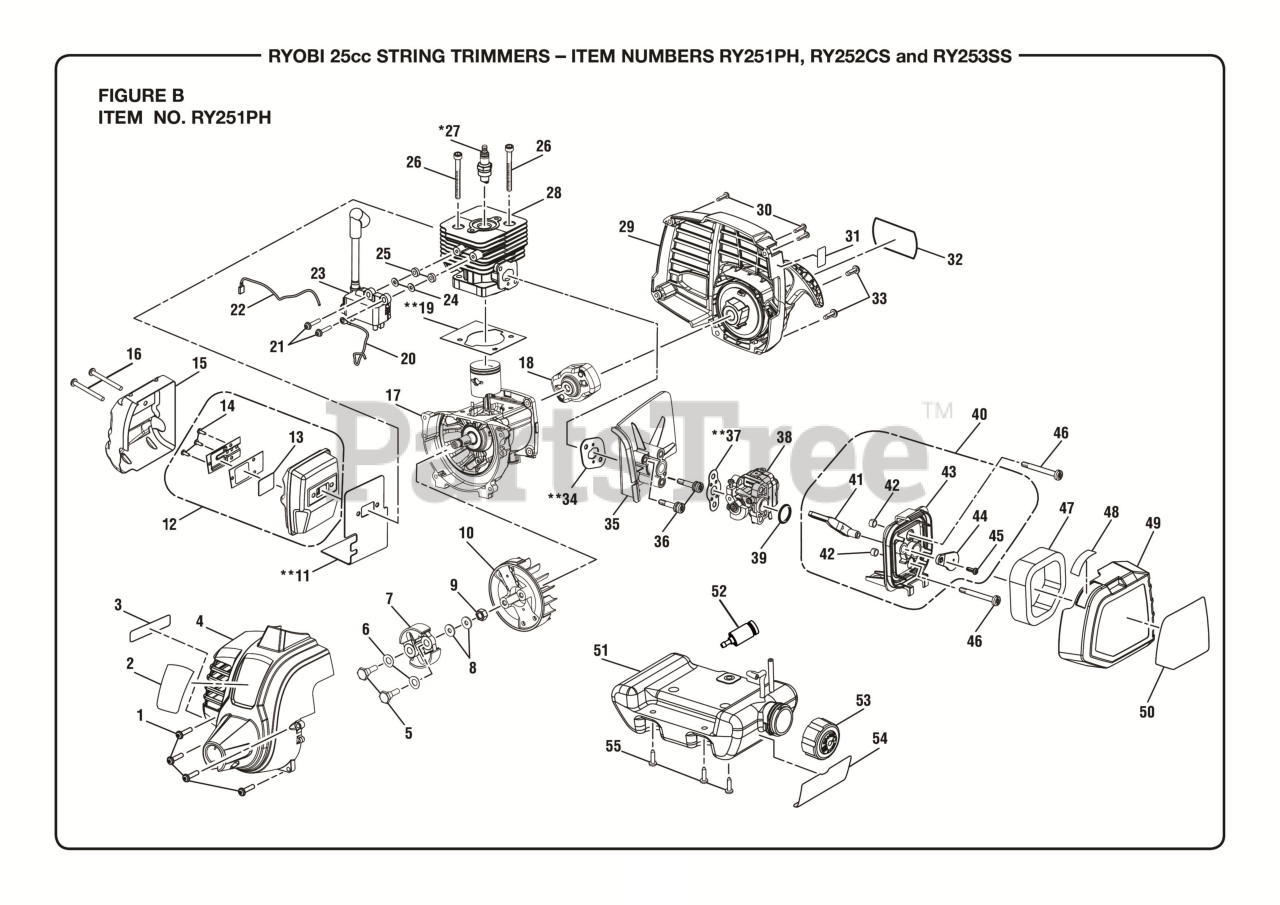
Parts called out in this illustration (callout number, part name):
1	Cap Screw w/Washer (M5 x 16 mm, T25 Torx Soc. Hd.)
2	Logo Label (Front)
3	Warning Label (Combustion)
4	Front Housing Assembly
5	Clutch Shoulder Bolt (M6 x 22.5 mm, Hex Hd.)
6	Washer (Curved)
7	Clutch Assembly
8	Washer (ID6 x OD15 x 1.2t)
9	Flange Nut (M8, Flywheel)
11	Muffler Gasket
12	Muffler Assembly
13	SCREEN
14	Screw (6-20 x 1/4 in., T20 Torx Pan Hd. S.T.)
15	HEAT SHIELD
16	Screw (M5 x 50 mm, Torx Slotted Recessed Pan Hd.)
17	Crankcase Assembly
18	Starter Cup
19	Gasket
20	Lead Wire Assembly, Red
21	Screw w/Washer (M4 x 19 mm, T20 Torx Pan Hd. S.T.)
22	Lead Wire Assembly, Black
23	Coil Boot Assembly
24	Flat Washer (OD10 x ID42 x 1t)
25	Phenolic Spacer (Ignition Module)
26	Screw (M5 x 22 mm, T25 Torx Soc. Hd.)
27	SPARK PLUG (CHAMPION RCJ4)
29	Screw (M4 x 18 mm, T20 Torx Pan Hd. S.T.)
30	Screw (M4 x 1.41 mm x 18 mm, T20 Torx Pan Hd. T.F)
31	Primer Bulb Location Label
32	Shoulder Screw (M4 x 14 mm, T25 Torx Truss Hd.
33	Cap Screw w/Washers (M5 x 16 mm, T25 Torx Soc. Hd.)
34	Gasket (Heat Dam)
35	Screw (M5 x 30 mm, T25 Torx Pan Hd. S.T.)
36	Screw (M5 x 27 mm, T25 Torx Pan Hd. S.T.)
37	Gasket
38	Carburetor Assembly
39	Carburetor O-Ring
40	Airbox Base Assembly
41	Compression Limiters
42	Washer (ID5.8 x OD11.5 x 1.7t)
43	Air Box Base
44	Screw (M4 x 12 mm, T20 Torx Pan Hd. S.T.)
45	Screw (M4 x 12 mm, Slotted Recessed Pan Hd.)
46	Screw (M5 x 44 mm,T25 Torx Hd. Carburetor)
47	Air Filter (Element)
48	Choke Position Label
49	Airbox Cover (Inc. Key Nos. 48 & 50)
50	Starting Instructions Label
51	Fuel Tank and Cap Assembly
52	Fuel Filter
53	Fuel Cap Assembly (1.5 in. Diameter)
54	Fuel Mixture Label
55	Shoulder Screw w/Washer (M4 x 14 mm, T25 Torx Truss Hd.)
